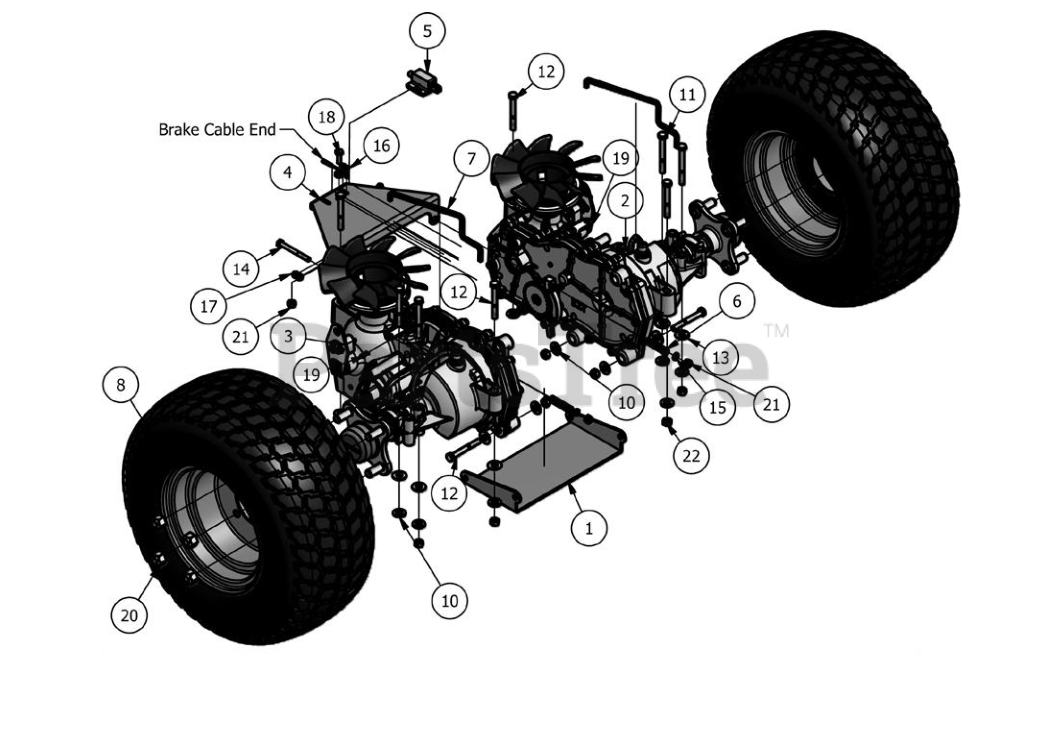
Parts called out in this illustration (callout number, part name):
1	Trans Axle Support Lower
3	EZT (Left)
4	Brake Lock Bracket
5	Safety Switch
6	Brake Spring
8	18 x 9.5-8 Tire and Wheel Assembly 48" Deck Only
9	18 x 7.5 8 Tire and Wheel Assembly 42" Deck Only
10	5/16 Lock Washer Zinc
11	5/16-18 X 2-3/4 Hex Bolt - Grade 5
12	5/16 x 2 1/2 Bolt
13	5/16 USS Flat Washer Zinc
14	1/4-20 x 2-1/2 Grade 5 Hex bolts Zinc
15	1/1 USS Flat Washer Zinc
16	10-24 x 3/4 Button Socket C/S 18-8 SS
17	10-24 Nylon Insert Locknut Zinc Orange Nylon
18	1/4-20 x 3/4 Grade 5 Hex bolts Zinc
19	Cotter Pin
20	Acorn Lug Nut
21	1/4-20 Nylon Insert Locknut Zinc Orange Nylon
22	5/16-18 Hex Nuts Zinc
23	18 x 9.50-8 Rear Tire Only 48 MZ
24	Rear Wheel 48 MZ
25	18 x 7.50-8 Rear Tire Only 42 MZ
26	Rear Wheel 42 MZ
